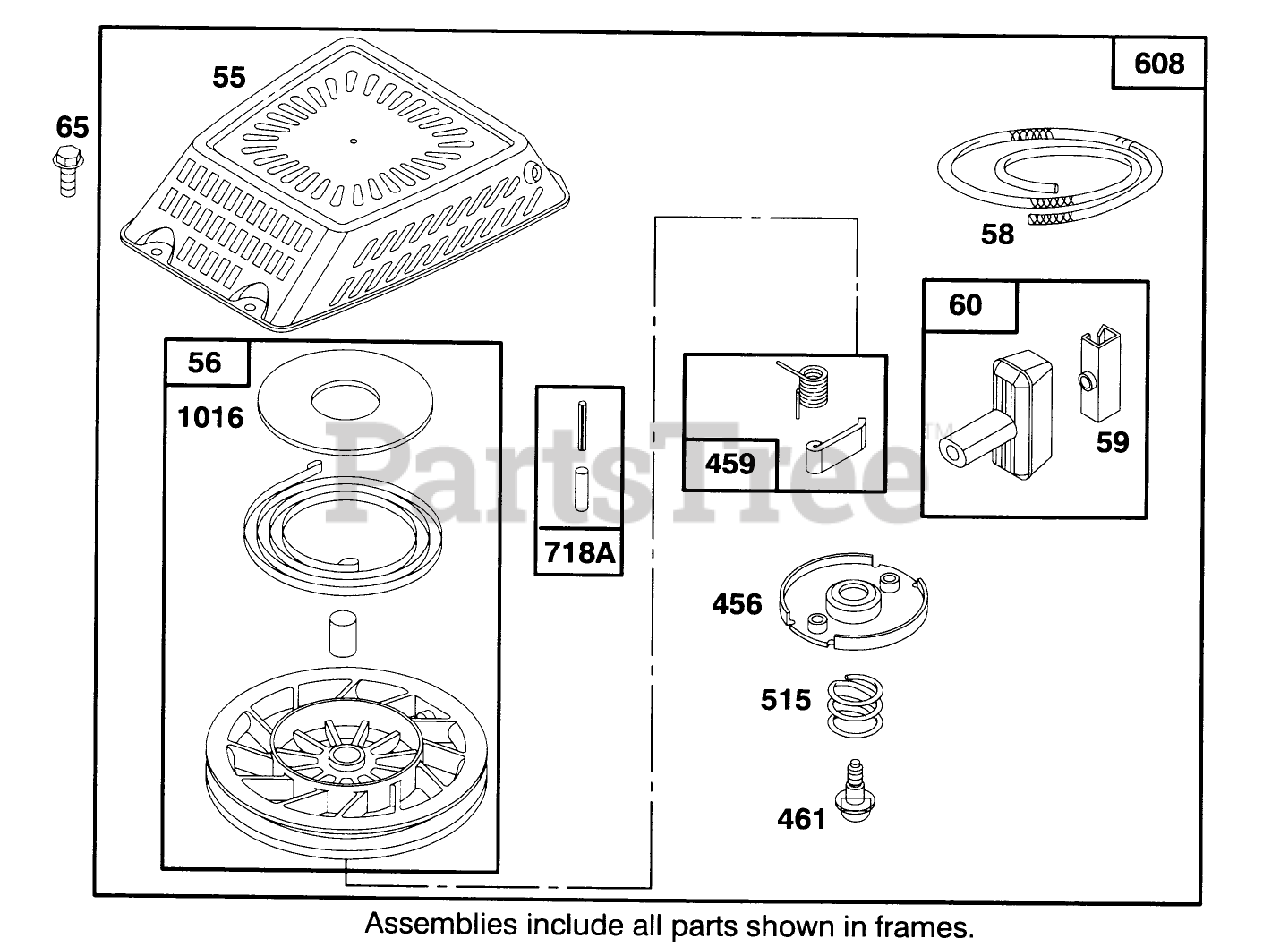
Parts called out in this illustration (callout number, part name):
59	INSERT-HANDLE, REWIND
456	RETAINER - SPRING
515	SPRING - RETAINER
